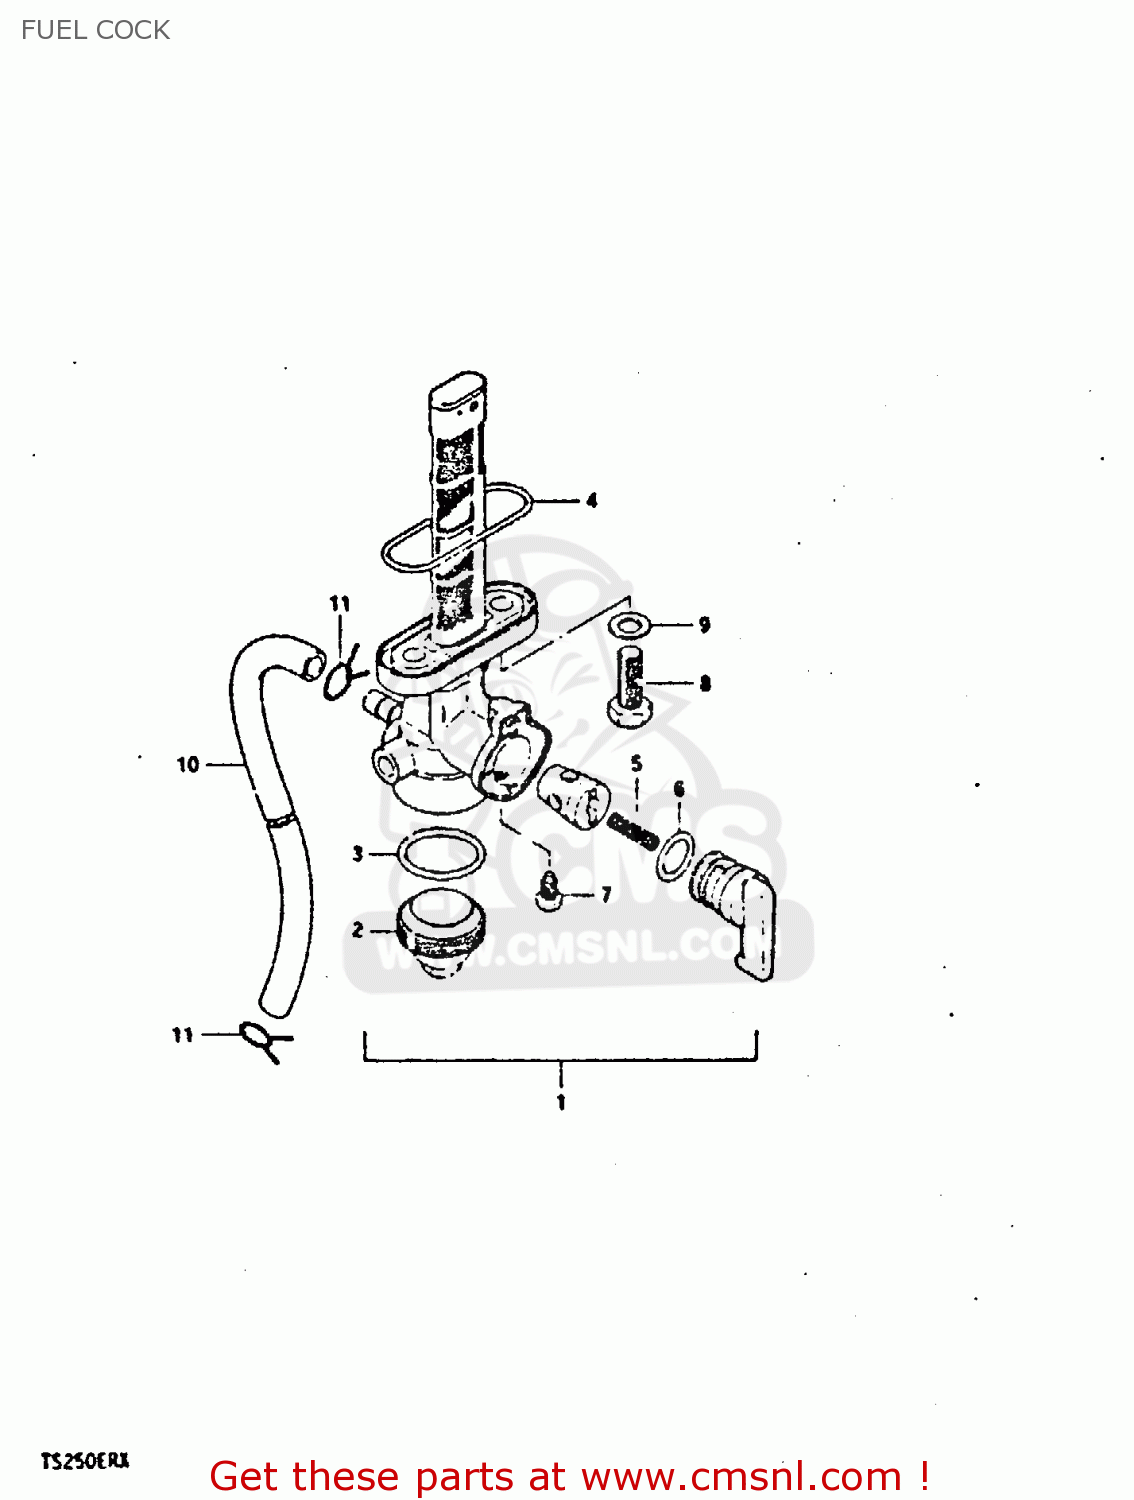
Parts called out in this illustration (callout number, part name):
1	COCK ASSEMBLY,FUEL
2	CUP,STRAINER
3	GASKET,FILTER (NAS)
4	O RING,FUEL COCK
5	SPRING
6	O-RING
7	SCREW
8	BOLT(6X20)
9	GASKET
10	HOSE
11	CLIP
